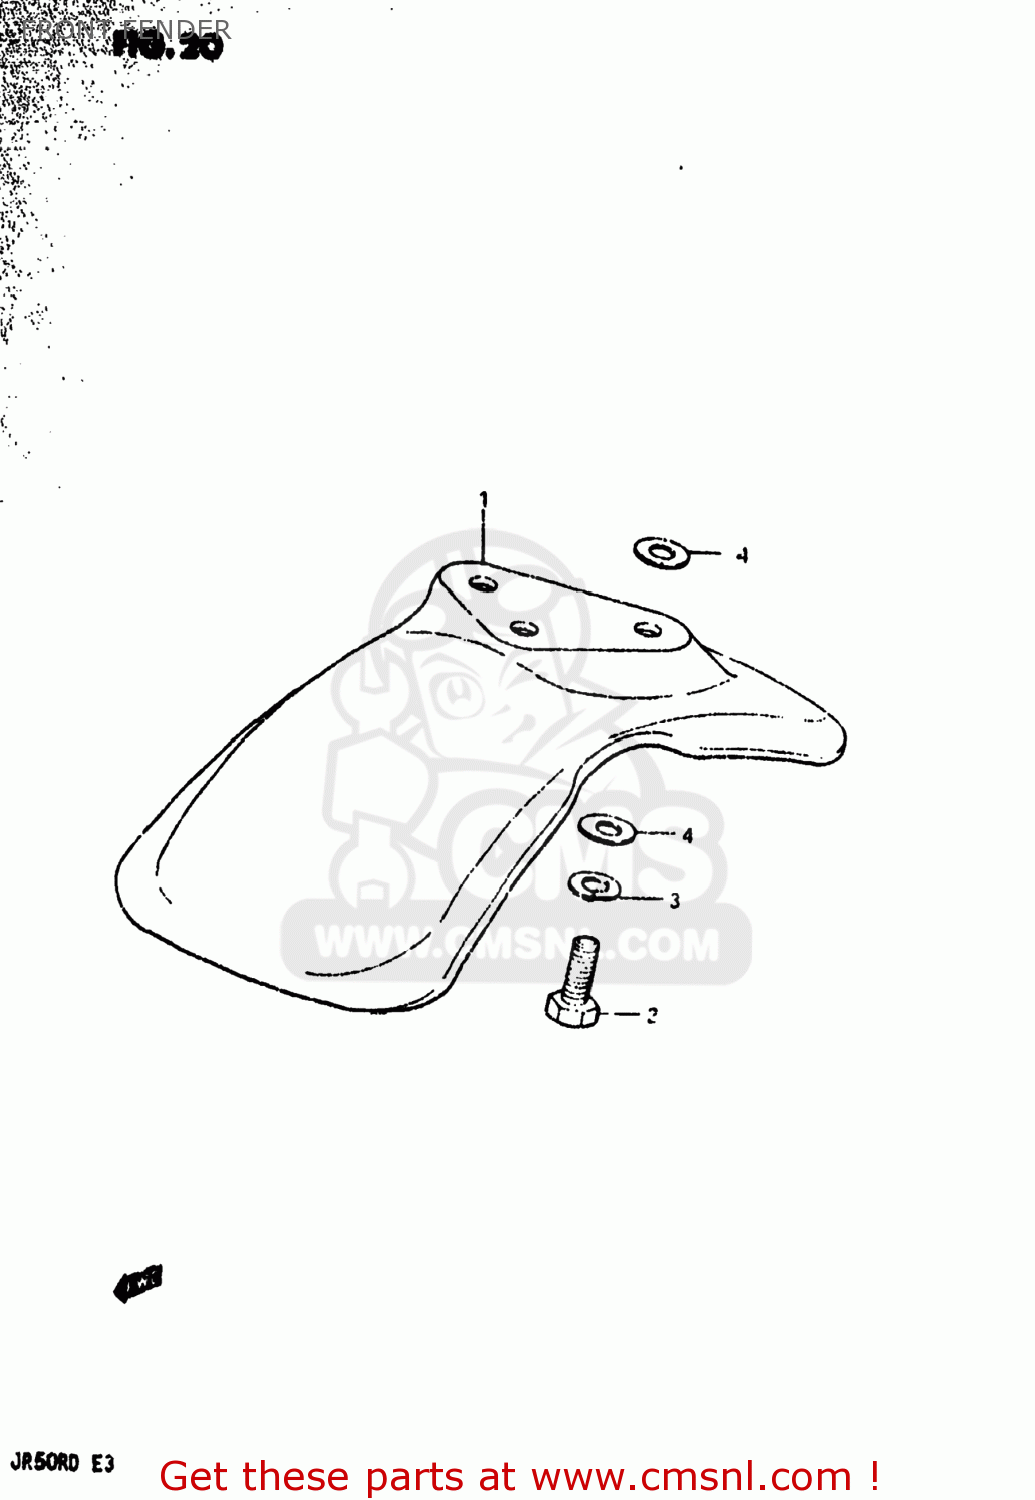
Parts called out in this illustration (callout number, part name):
1	FENDER,FRONT
2	BOLT
3	LOCK WASHER
4	WASHER(6.5X18X1)
